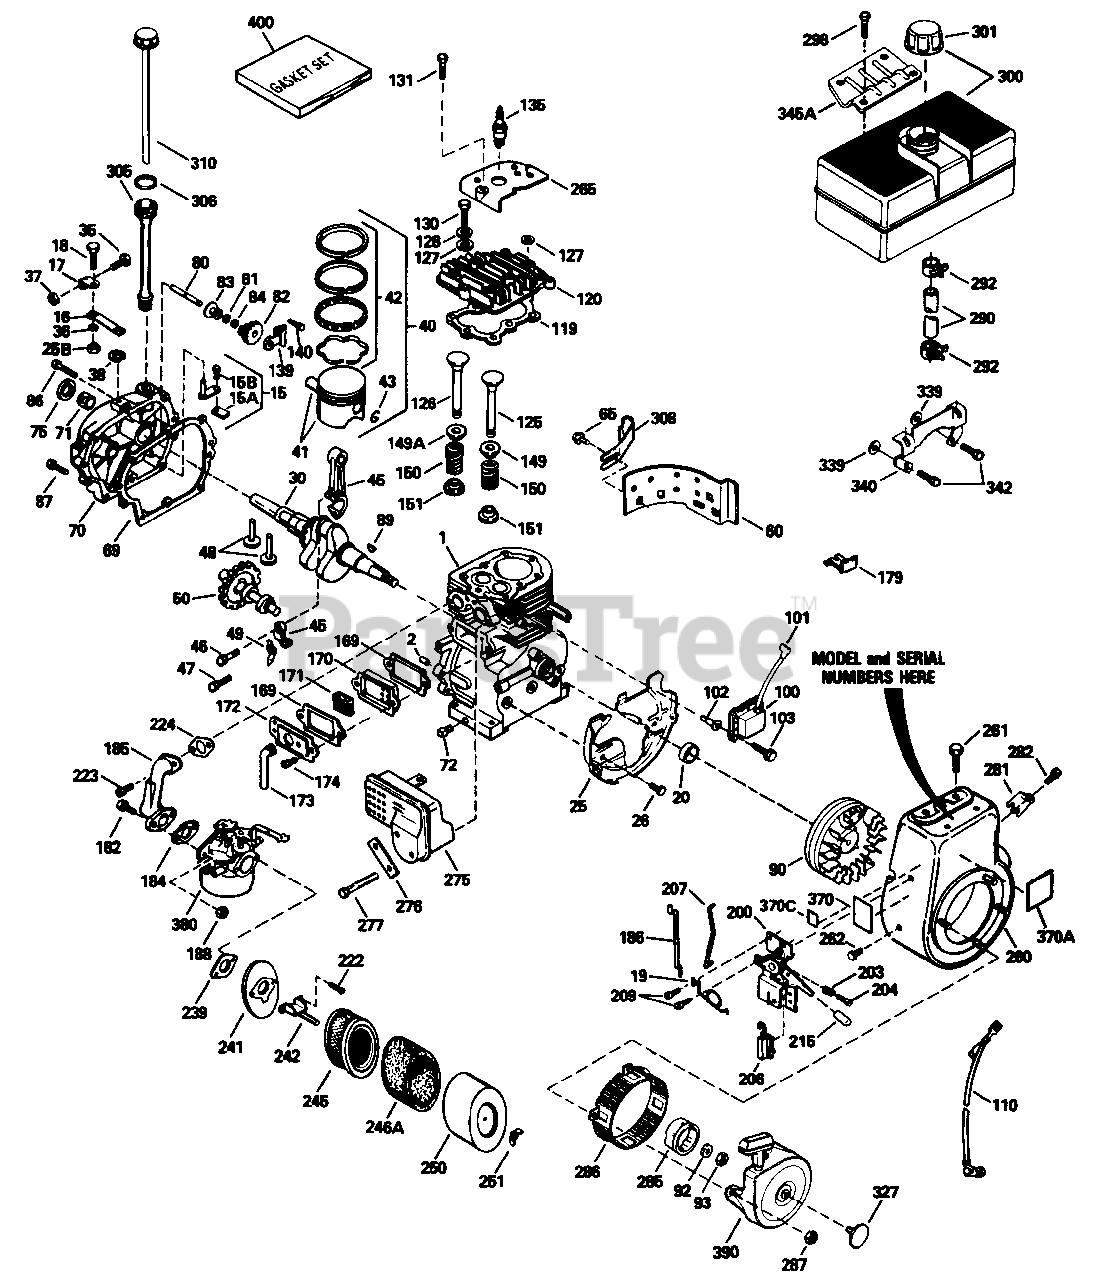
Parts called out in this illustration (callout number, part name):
1	Cylinder
2	Pin, Dowel
15	Rod Ass'y., Governor
15A	Yoke, Governor
15B	Screw, Fil. Hd. Sems, 6-40 x 5/16
16	Lever, Governor
17	Clamp, Governor Lever
18	Screw, Hex Washer Hd., 8-32 x 5/16
19	Spring, Speed Control
20	Seal, Oil
25	Baffle, Blower Housing
25B	Lock Nut, Hex "Keps," 8-32
26	Screw, Hex Washer Hd. Durlok, 1/4-20 x 5/8
30	Crankshaft
35	Screw, Hex Washer Hd., 10-32 x 3/4
36	Washer, E.T. Lock
37	Lock Nut, Hex "Keps," 10-32
38	Ring, Retaining
40	Piston, Pin & Ring Ass'y.
40	Piston, Pin & Ring Ass'y. (.010 Oversize)
40	Piston, Pin & Ring Ass'y. (.020 Oversize)
41	Piston & Pin Ass'y. (Std.)
41	Piston & Pin Ass'y. (.010 Oversize)
41	Piston & Pin Ass'y. (.020 Oversize)
42	Ring Set, Piston (Std.)
42	Ring Set, Piston (.010 Oversize)
42	Ring Set, Piston (.020 Oversize)
43	Ring, Piston Pin Retaining
45	Rod Ass'y., Connecting
46	Bolt, Connecting Rod
47	Bolt, Connecting Rod
48	Lifter, Valve
49	Dipper, Oil
50	Camshaft (Mechanical Compression Release)
60	Extension, Blower Housing
65	Screw, Hex Hd. Sems, 10-24 x 1/2
69	Gasket, Cylinder Cover
70	Cover Ass'y., Cylinder
71	Bushing, Cylinder Cover
72	Plug, Pipe
75	Seal, Oil
80	Shaft, Governor
81	Washer, Flat
82	Gear, Governor
83	Spool, Governor
84	Ring, Retaining
86	Screw, Hex Washer Hd. Power Lok, 1/4-20 x 1-3/16
87	Screw, Hex Washer Hd. Power Lok, 1/4-20 x 1-11/16
89	Key, Flywheel
92	Washer, Lock
93	Nut, Flywheel
100	Solid State Ass'y.
101	Cover, Spark Plug
102	Stud, Solid State Mounting
103	Screw, Torx Hex Washer Hd., Sems, 10-24 x 1
110	Wire, Ground
119	Gasket, Cylinder Head
120	Head, Cylinder
125	Valve, Exhaust (Std.)
125	Valve, Exhaust (1/32" Oversize)
126	Valve, Intake (Std.)
126	Valve, Intake (1/32" Oversize)
127	Washer, Flat
128	Washer, Belleville
130	Screw, Hex Flange Hd., 5/16-18 x 2
131	Screw, Hex Washer Hd. Taptite, 1/4-20 x 5/8
135	Spark Plug
139	Bracket, Governor Gear
140	Screw, Hex Washer Hd. Thread Forming, 10-24 x 1/2
149	Cap, Upper Valve Spring
149A	Seal Ass'y., Intake Valve
150	Spring, Valve
151	Cap, Lower Valve Spring
169	Gasket, Breather
170	Body, Breather
171	Element, Breather
172	Cover, Breather
173	Tube, Breather
174	Screw, Hex. Hd. Sems, 10-24 x 1/2
179	Clip, Wire
182	Screw, Fil. Hd. Sem, 1/4-28 x 1
184	Gasket, Carburetor
185	Pipe, Intake
186	Link, Governor
188	Nut, Whiz Lock, 1/4-28
200	Bracket Ass'y., Control
203	Spring, Compression
204	Screw, Fil. Hd., 5-40 x 7/16
206	Terminal Ass'y.
207	Link, Governor-to-Throttle
209	Screw, Hex Washer Hd. Thread Cutting, 10-32 x 1/2
215	Knob, Control
222	Screw, Fil. Hd. Sems, 10-32 x 1/2
223	Screw, Torx Fil. Hd., Sems 5/16-18 x 1-1/8
224	Gasket, Intake Pipe
239	Gasket, Air Cleaner
241	Bracket, Air Cleaner
242	Bracket, Air Cleaner
245	Element, Air Cleaner
246A	Filter, Pre-Air Cleaner (Poly)
250	Cover, Air Cleaner
251	Nut, Wing 1/4-20
260	Housing, Blower
261	Screw, Hex Hd., Spinlock Thread Forming, 5/16-18 x 3/4
262	Screw, Phil. Hex Hd. Sems, 5/16-24 x 21/32
265	Cover, Cylinder Head
275	Muffler
276	Plate, Lock
277	Screw, Hex Hd., 5/16-18 x 3-3/16
281	Cover, Starter Hole
282	Screw, Pan Hd. Taptite, 8-32 x 3/8
285	Hub, Starter
286	Screen, Starter
287	Nut & Lock Washer, 1/4-28
290	Line, Fuel
292	Clamp, Fuel Line
298	Screw, Hex Washer Hd. Thread Cutting, 1/4-15 x 7/8
300	Tank, Fuel
301	Cap, Fuel Tank
305	Tube, Oil Filler
306	Gasket, Dipstick
308	Clip, Oil Fill Tube
310	Dipstick, Oil
327	Plug, Starter
339	Spacer, Tank Bracket
340	Bracket, Fuel Tank
342	Screw, Hex Washer Hd. Durlok, 1/4-20 x 5/8
345A	Plate, Fuel Tank Mounting
370	Decal, Instruction
370A	Decal, Name
370C	Decal, Throttle
380	Carburetor
390	Starter, Rewind
400	Gasket Set
